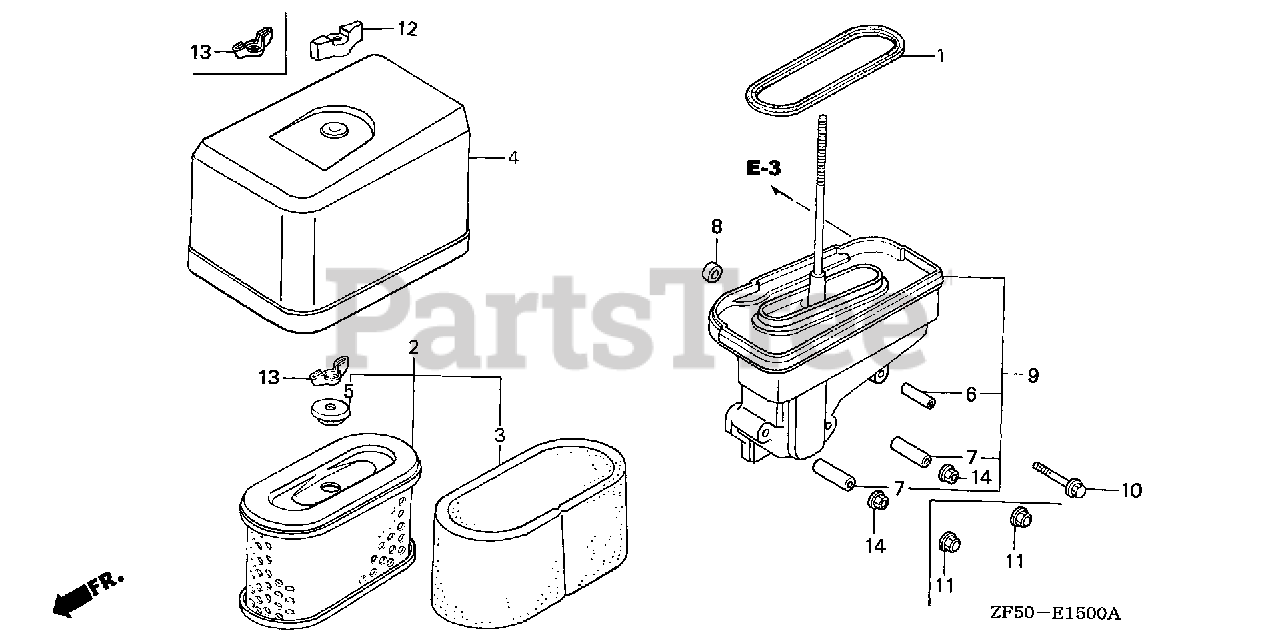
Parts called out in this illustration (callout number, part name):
1	GASKET, ELBOW
2	ELEMENT, AIR CLEANER (METAL BASE)
3	FILTER (OUTER)
4	COVER, AIR CLEANER (DUAL)
5	GROMMET, AIR CLEANER
6	COLLAR, AIR CLEANER
7	COLLAR, AIR CLEANER
9	ELBOW, AIR CLEANER
10	BOLT, FLANGE (6X35) (CT200)
11	NUT, CAP (6MM)
12	WINGNUT (6MM) (BLACK)
13	NUT, TOOL BOX SETTING
